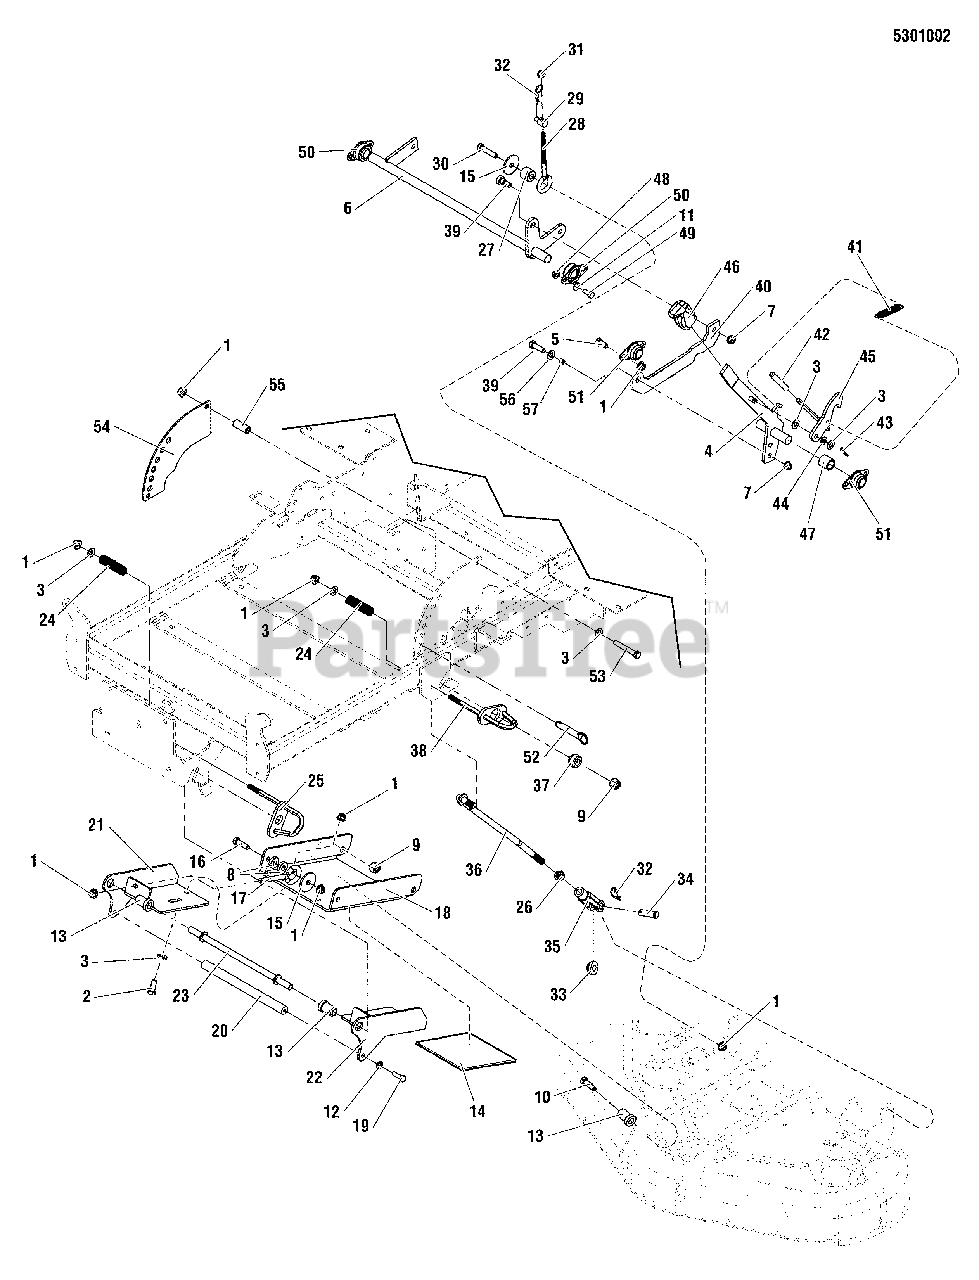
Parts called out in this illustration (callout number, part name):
1	NUT, 3/8-16 HEX NYLOCK FLANGE
2	BOLT, 3/8-16 X 1" GD5 CZ
3	WASHER, 3/8 SAE
4	WELD, HANDLE, DECK LIFT - RED
5	BOLT, 3/8-16 X 3/4" GD5 CZ
6	WELD, SHAFT, REAR DECK LIFT - RED
7	NUT, 3/8-16 HEX NYLOCK FLANGE
8	SPACER, .39 X 1.00 X .25
9	NUT, Hex, Nylon Lock, 1/2-20
10	BOLT, 1/2-20 X 2-1/2" GD5 CZ
11	WASHER, 5/16" SAE
12	WASHER, 5/16 LOCK YZ
13	SPACER, .53 X 1.00 X 1.00
14	SAFETY WALK, 4.50 X 3.50
15	WASHER, .41 X 1.75 X .14
16	BOLT, 3/8-16 X 1-1/4" GD5 CZ
17	EYE BOLT, 3/8-16 X 5, 2.88THRD, 1EYE, CZ
18	PLATE, DECK HANGER SUPPORT
19	BOLT, 5/16-18 X 1 GD5 YZ
20	SHAFT, HANDLE, DECK MOUNT
21	WELD, DECK HANGER, RH
22	WELD, DECK HANGER, LH
23	SHAFT, HANGER
24	SPRING, COMPRESSION
25	WELD, QUICK RELEASE HANDLE - RED
26	NUT, 1/2-20 HEX JAM
27	SPACER, .39 X 1.00 X .88
28	EYE BOLT, 3/8-16 X 6, 3.0 THRD, 1 EYE
29	ADJUSTER, BRAKE LINKAGE
30	BOLT, 3/8-16 X 1-3/4" GD5 CZ
31	NUT, 3/8-16 HEX NYLON LOCK
32	PIN, 3/32 X 0.750, COT, ZINC/CLEAR
33	BUSHING, DECK SUPPORT
34	PIN, CLEVIS, 1/2 X 1 1/2, YZP
35	CLEVIS, 1/2-20, STEEL
36	ROD, DECK LIFT LINKAGE
37	BUSHING, REAR QUICK TACH
38	WELD, QUICK RELEASE HANDLE, REAR - RED
39	BOLT, 3/8-16 X 1-1/4" GD5 CZ
40	LINK, DECK LIFT SHAFT
41	SPRING, EXTENSION
42	COVER, VINYL HANDLE
43	PIN, COTTER, 1/8" X 3/4
44	WASHER, WAVE, M10
45	WELD, DECK LOCK
46	GRIP, BLACK FLEXIBLE
47	SPACER, .76 X 1.00 X 1.00
48	NUT, 5/16-18 HEX NYLOCK FLANGE
49	BOLT, 5/16-18 X 3/4 GD5
50	BEARING, BRONZE FLANGE, 3/4"
51	BEARING, BRONZE FLANGE, 3/4
52	HITCH PIN ASSEMBLY, 1/2" X 2.50"
53	BOLT, 3/8-16 X 2-1/2" GD5 CZ
54	PLATE, DECK HEIGHT- INNER -RED
55	SPACER, .39 X .63 X 1.50
56	WASHER, 3/8 SAE
57	SPACER, .38 X .50 X .38, YZ
